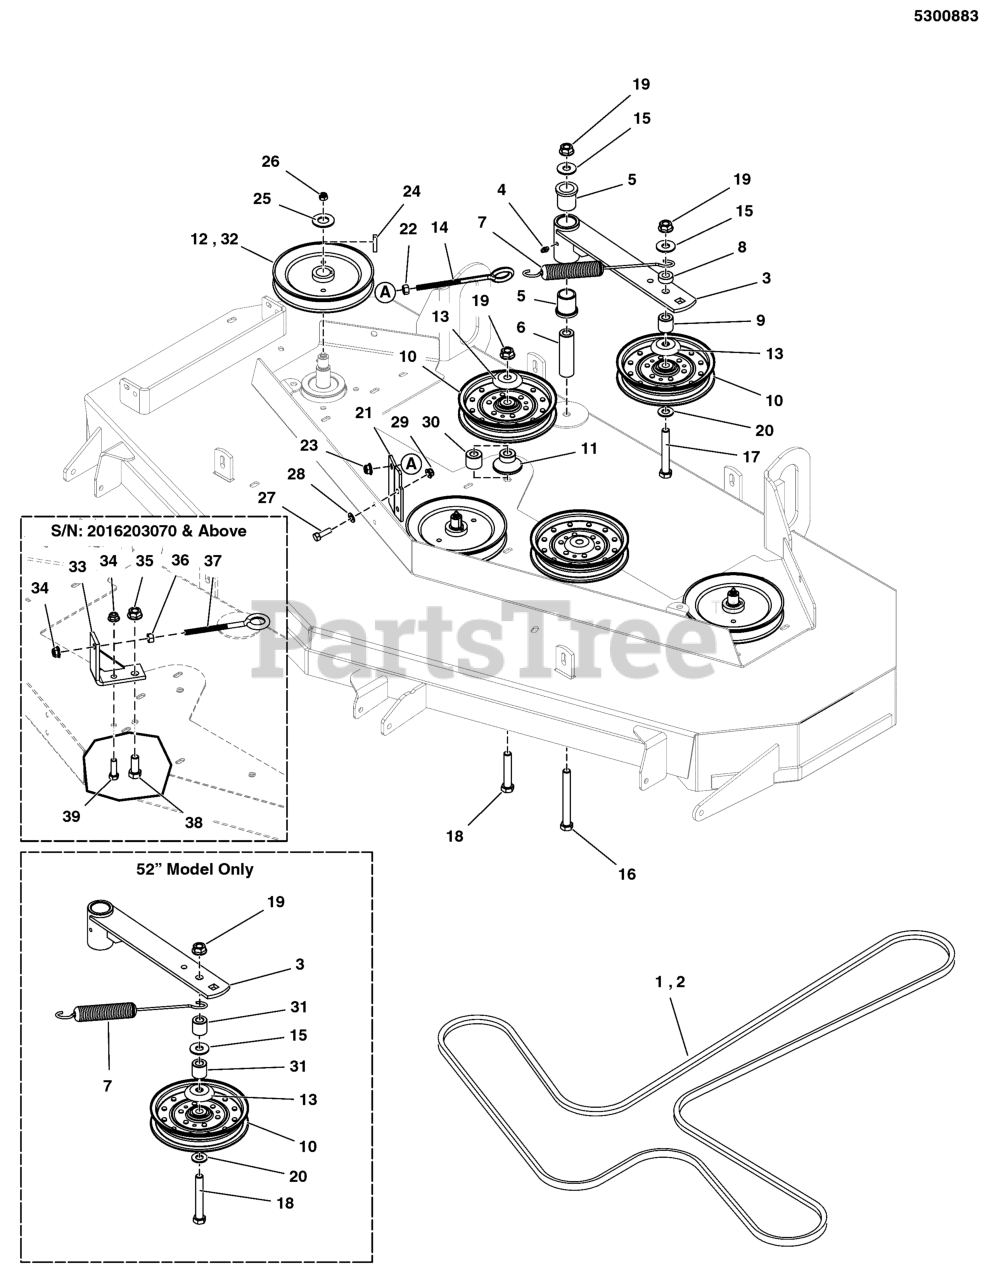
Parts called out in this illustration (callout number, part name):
1	BELT, BP-SEC, 173.90EL, ARAMID, WRPD
2	BELT, BP-SEC, 156.906EL, LRG ARAMID, WRPD
3	WELD, IDLER ARM
4	GREASE FITTING, 1/4-28 STR
5	BUSHING, FLANGE
6	SPACER, .52 X 1.00 X 3.42
7	SPRING-EXT, 1.04ODX10.54LGX.148WR , BLK
8	SPACER, .52 X 1.00 X .38, CZ
9	SPACER, .52 X 1.00 X 1.00
11	IDLER MOUNT
12	PULLEY, 6.93 EOD X 25MM, SPLIT
13	SHIELD, PULLEY BEARING
14	EYE BOLT, 3/8-16 X 6.88, 3THRD, 1EYE
15	WASHER, 1/2" USS
16	BOLT, 1/2-13 X 4-1/2 GD5 YZ
17	BOLT, 1/2-13 X 3-1/2, HEX HD, GD5, CZ (SV)
18	BOLT, 1/2-13 X 2-3/4 GD5 CZ
19	NUT, Hex Flange, Nylock, 1/2-13
20	WASHER, 1/2 SAE
21	BRACKET, ANCHOR, BELT TENSION, 52/61-RED
22	NUT, 3/8-16 HEX, YZ
23	NUT, 3/8 - 16 HEX NYLOCK FLANGE
24	KEY, 1/4 SQ X 1-1/4
25	WASHER, 3/4 BELLEVILLE
26	NUT, 5/16-24 HEX NYLON LOCK
27	BOLT, 5/16-18 X 1" GRD5 YZ
28	WASHER, 5/16" SAE
29	NUT, 5/16-18 HEX NYLOCK FLANGE NUT
30	SPACER, .52 X 1.25 X .70, CZ
31	SPACER, .52 X 1.00 X .44, CZ
32	PULLEY-6.122 OD. X .98 BORE
33	WELD, SPRING ANCHOR, CCW-61 - RED
34	NUT, 3/8 - 16 HEX NYLOCK FLANGE
35	NUT, Hex Flange, Nylock, 1/2-13
36	NUT, 3/8-16 HEX, YZ
37	EYE BOLT, 3/8-16 X 6, 3THRD, 1EYE, CZ
38	BOLT, 1/2-13 X 1-1/4 GD5 CZ
39	BOLT, 3/8-16 X 1-1/4" GD5 CZ
